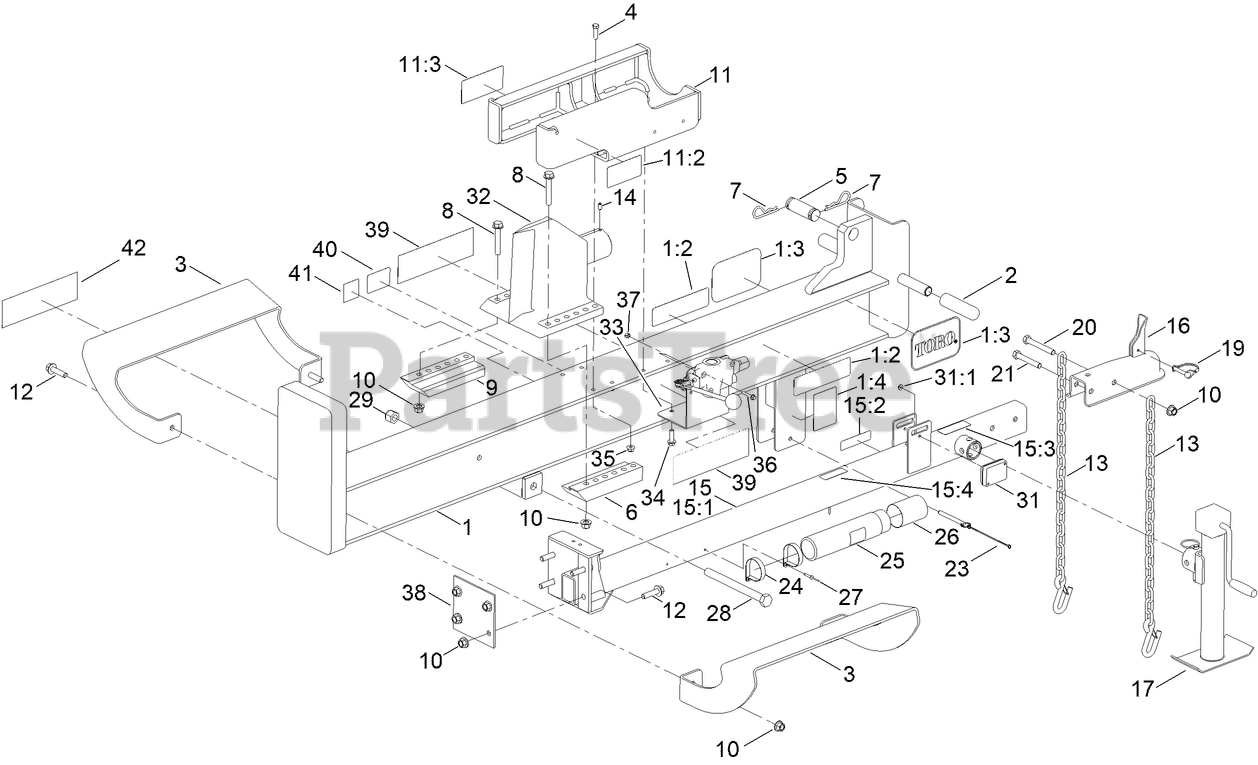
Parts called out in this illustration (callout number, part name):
1	BEAM ASM
1:3	DECAL
1:4	DECAL-WARNING, PIN
2	GRIP-HANDLE
3	PLATE-CATCH
4	SCREW-HH
5	PIN-PIVOT
6	BAR-SLIDE, LH
7	PIN-HAIR
8	SCREW-HF
9	BAR-SLIDE, RH
10	NUT-LOCK
11	DISLODGE BRACKET W/DECALS
11:2	DECAL-WARNING, PINCH POINT
11:3	DECAL-CAUTION, DANGEROUS AREA
12	SCREW-HF
13	CHAIN-SAFETY, TRAILER
14	SCREW-SET
15	DECAL ASM-TUBE
15:1	TONGUE ASM [RED]
15:2	DECAL-ARRESTOR, SPARK
15:3	DECAL-CAUTION
15:4	DECAL-WARNING, PINCH POINT
16	RECEIVER-BALL HITCH
19	PIN-LOCK
20	SCREW-HH
21	SCREW-HH
24	CLAMP-R
25	TUBE-MANUAL
26	CAP-HOUSING
27	RIVET-BLIND
28	BOLT-HH
29	NUT-LOCK, NI
31	LAMP-MARKER, FRONT SIDE
31:1	NUT-KEPS
32	WEDGE [BLACK]
33	BRACKET-VALVE
34	SCREW-HHF
35	NUT-HF, NI
36	SCREW-HHF
37	NUT-LOCK, NI
38	PLATE - BACKING
39	DECAL-RHHLG3X10
40	DECAL-CPER0011
41	DECAL-CPER0003
42	DECAL-CPER0002
